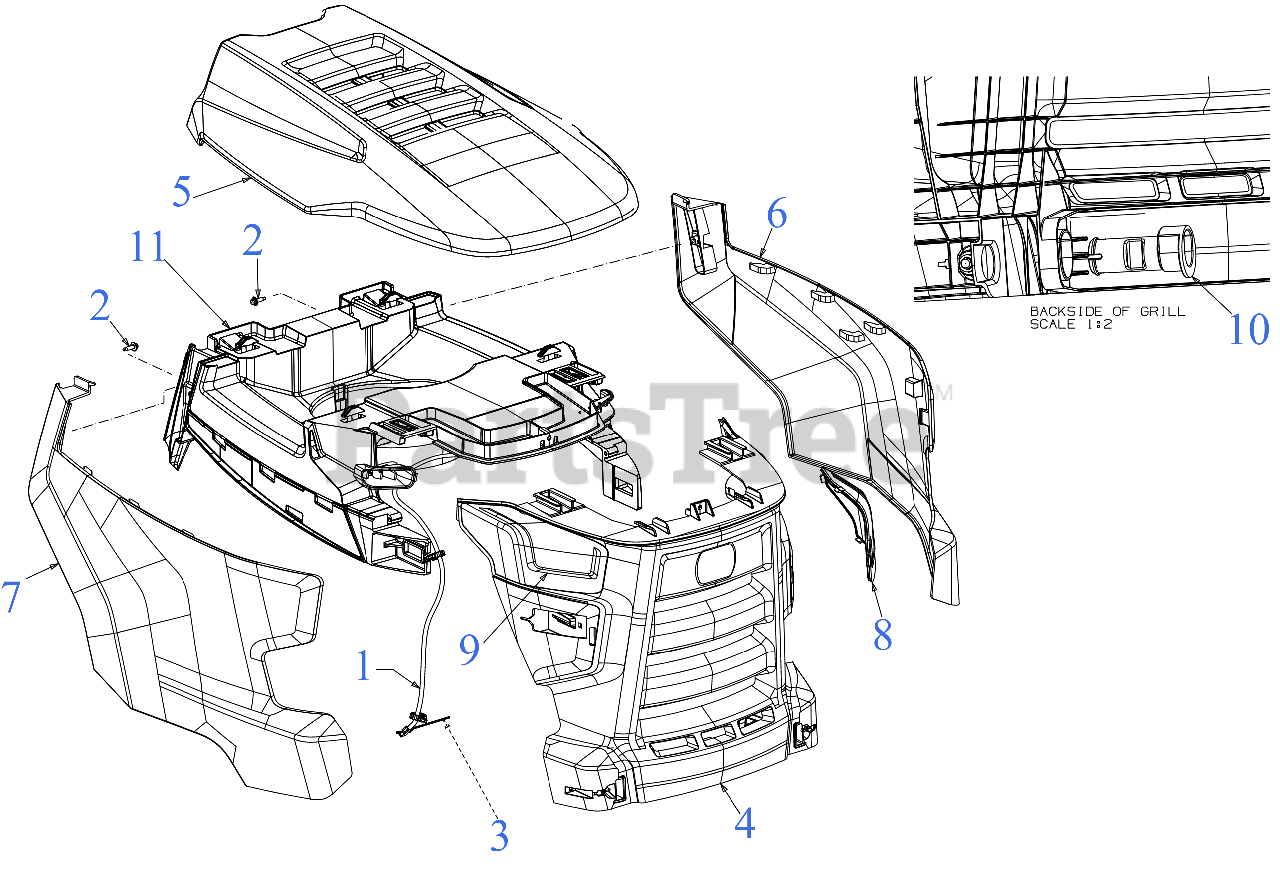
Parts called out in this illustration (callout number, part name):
1	HEADLIGHT HARNESS ASSEMBLY (W/LED)
2	SCREW 1/4-10 x .750
3	CABLE TIE
4	FRONT GRILLE (STYLE C)
5	HOOD TOP (YELLOW)
6	SIDE PANEL (LH)
7	SIDE PANEL (RH)
8	LED HEADLIGHT LENS (LH)
9	LED HEADLIGHT LENS (RH)
10	HOOD PIVOT PIN
11	HOOD PLENUM
